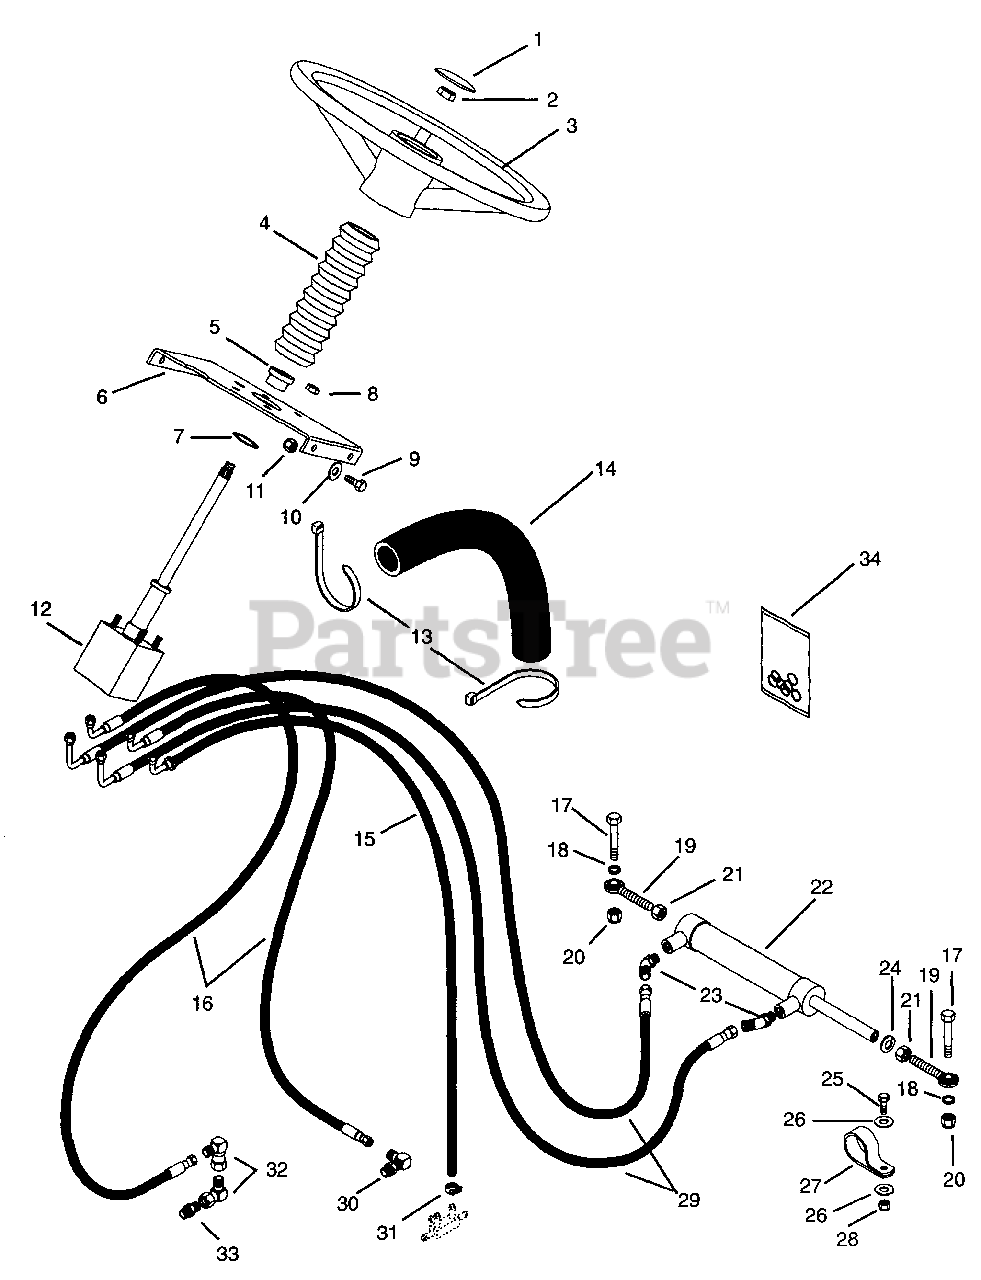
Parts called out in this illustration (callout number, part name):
1	Steering Wheel Cap
2	Nut-Hex .62-11
3	Steering Wheel
4	Steering Column Boot
5	Bushing-Flange .762 x 1.0 x .580 x 1.48
6	Bracket, Steering Pump
7	Ring-Retaining-External 1.31 x .05
8	Nut-Locking-Center .31-24
9	Bolt-Hex .25-20 X 1.25 Grade 5
10	Washer-Flat-Steel .344 x .688 x .065
11	Nut-Locking-Center .31-18
12	Power Steering Unit
13	Tie Wrap, Black
14	Sleeve 12"
15	Assembly, Hydraulic Hose
16	Assembly, Hydraulic Hose
17	Bolt-Hex .50-13 x 2.00 Grade 5
18	Spacer .520 x .625 x .125
19	Assembly, Rod End
20	Nut-Locking-Center .50-13
21	Nut-Jam .50-20 Grade 2
22	Cylinder, Steering
23	Adapter
24	Washer-Locking .50 X 1.25
25	Bolt-Hex .38-16 x 1.00 Grade 5
26	Washer-Flat-Steel .406 x .812 x .065
27	Clamp, Nylon
28	Nut-Locking-Nylon .38-16
29	Hydraulic Hose Assembly
30	Adapter
31	Hose Clamp
32	Adapter
33	Adapter-Pipe .56-18 "O" Ring To .56-18
34	Repair Kit, PM-400 Power Steering
